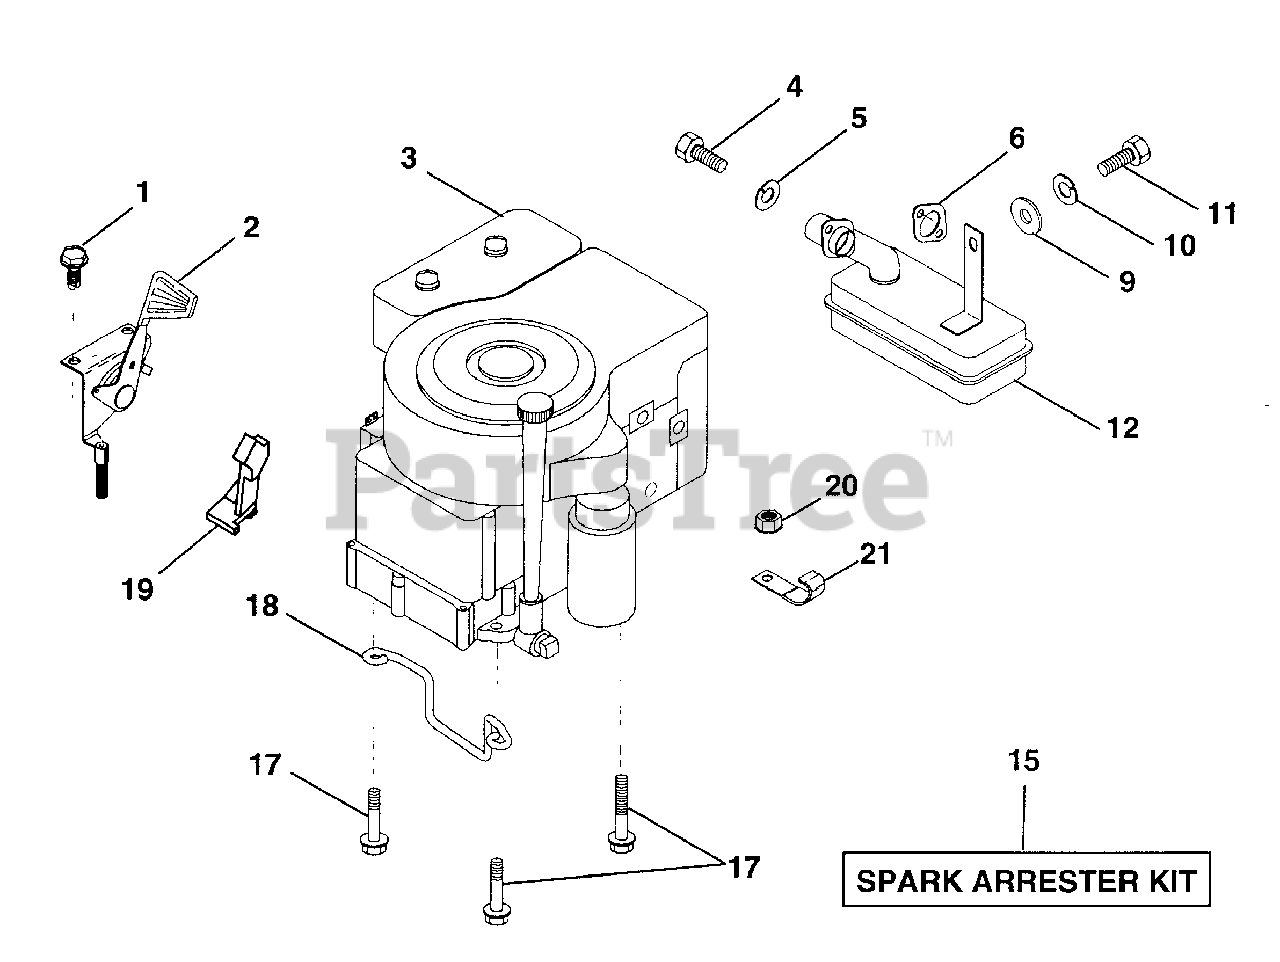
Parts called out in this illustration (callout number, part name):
1	Screw, Hex Thd. Cut 1/4-20 x 1/2
2	Control, Throttle
3	Engine, Briggs and Stratton Model No. 282707
4	Screw, Hex, Cap 5/16-18 x 3/4
5	Washer, Lock Heavy Helical Spring 5/16
6	Gasket, Exhaust
9	Washer 5/16 x 3/4 x 16
10	Washer, Lock Hvy Hlcl Spring 1/4
11	Bolt, Hex Fin.
15	Arrester, Spark
17	Screw, Hex Washer Head, Thdrol. 3/8-16 x 1-1/2
18	Keeper, Ground Drive Belt
19	Stop, Throttle
20	Screw Thdrol. 3/8-16
21	Clip Line Fuel
